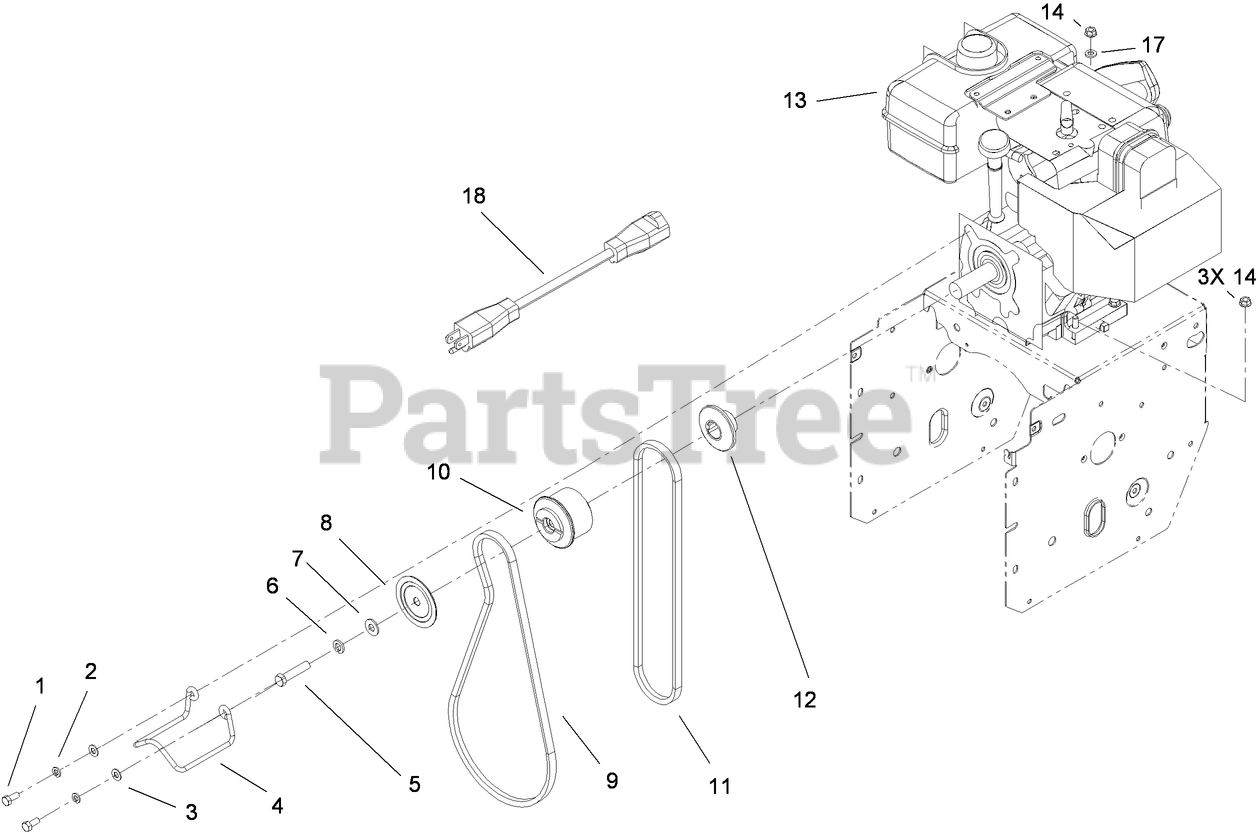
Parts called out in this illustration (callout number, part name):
1	SCREW-HH
2	WASHER-LOCK
3	WASHER-PLAIN
5	SCREW-HH
6	WASHER-LOCK
7	WASHER-FLAT
8	SHEAVE-HALF, IMPELLER
9	BELT-V
10	PULLEY-ENGINE, CENTER
11	V BELT-TRACTION
12	SHEAVE-HALF, TRACTION
13	ENGINE-TECUMSEH, LH358SA-159625A ES
14	NUT-HF
17	WASHER-FLAT
18	CORD-EXTENSION (only on: 38078)
